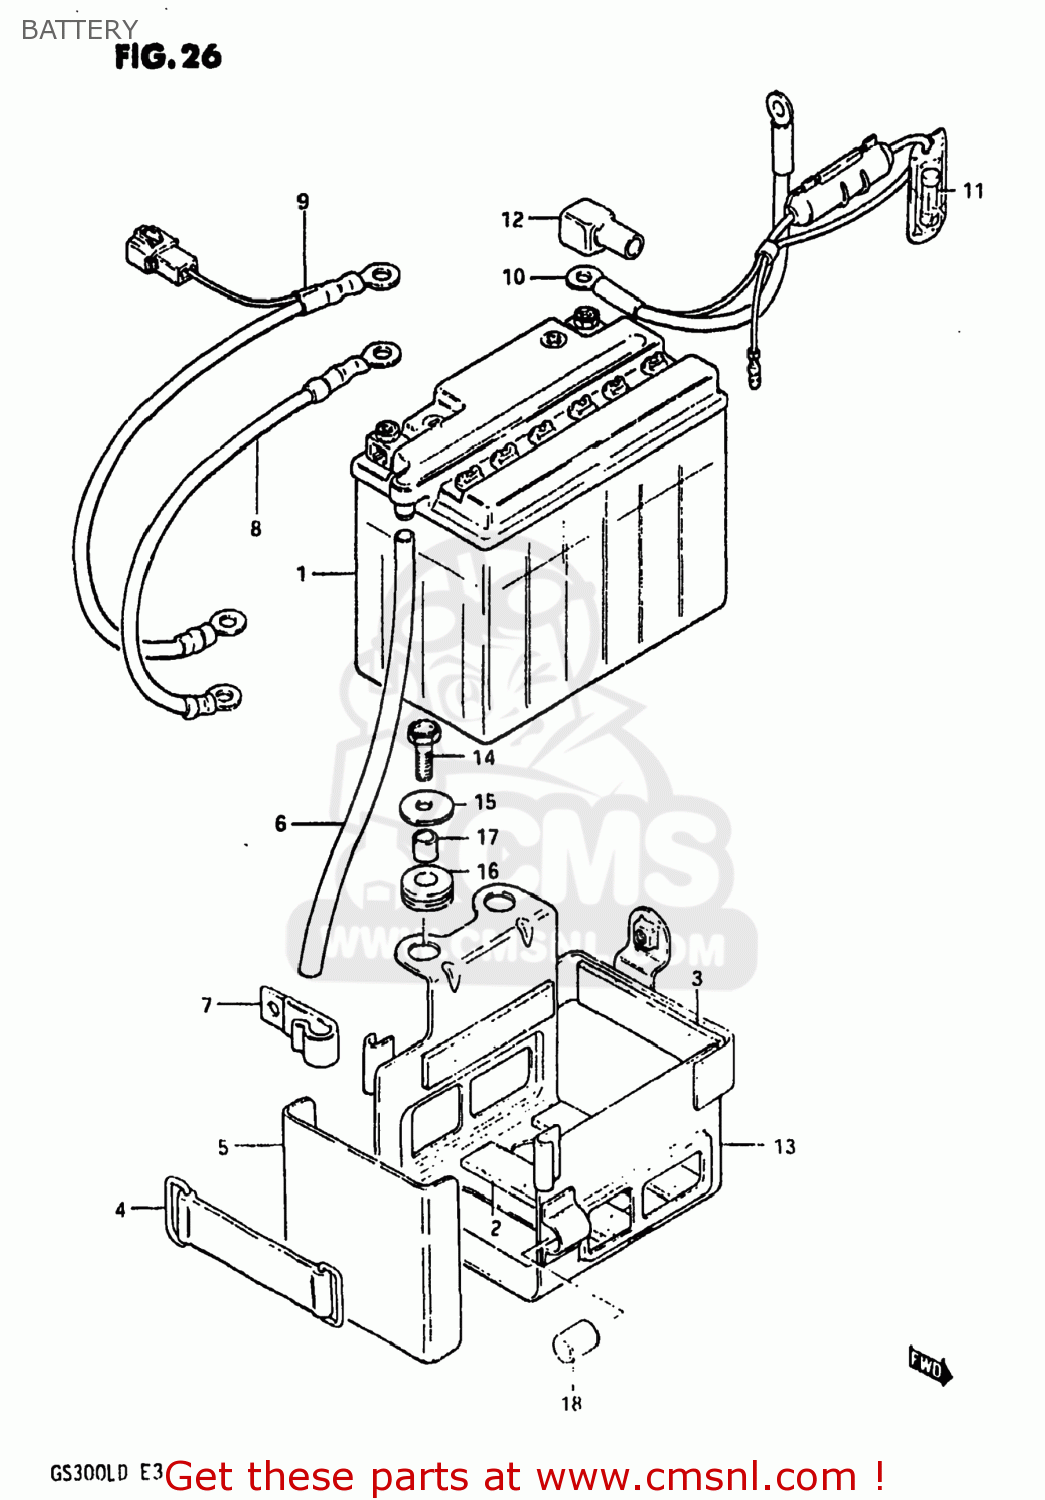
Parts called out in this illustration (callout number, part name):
1	BATTERY ASSEMBLY (12V)
2	PROTECTOR(20X90)X4
3	PROTECTOR,20X9
4	BAND
5	COVER,BATTERY
6	HOSE,BATTERY EXHAUST
7	CLAMP
8	LEAD WIRE,BATTERY(-)
9	CORD,BATTERY MINUS
10	FUSE CASE AND PLUS CABLE
11	FUSE(15A)
12	CAP,TERMINAL
13	HOLDER,BATTERY
14	BOLT
15	WASHER
16	CUSHION
17	SPACER (6.1X9X9)
18	CUSHION
